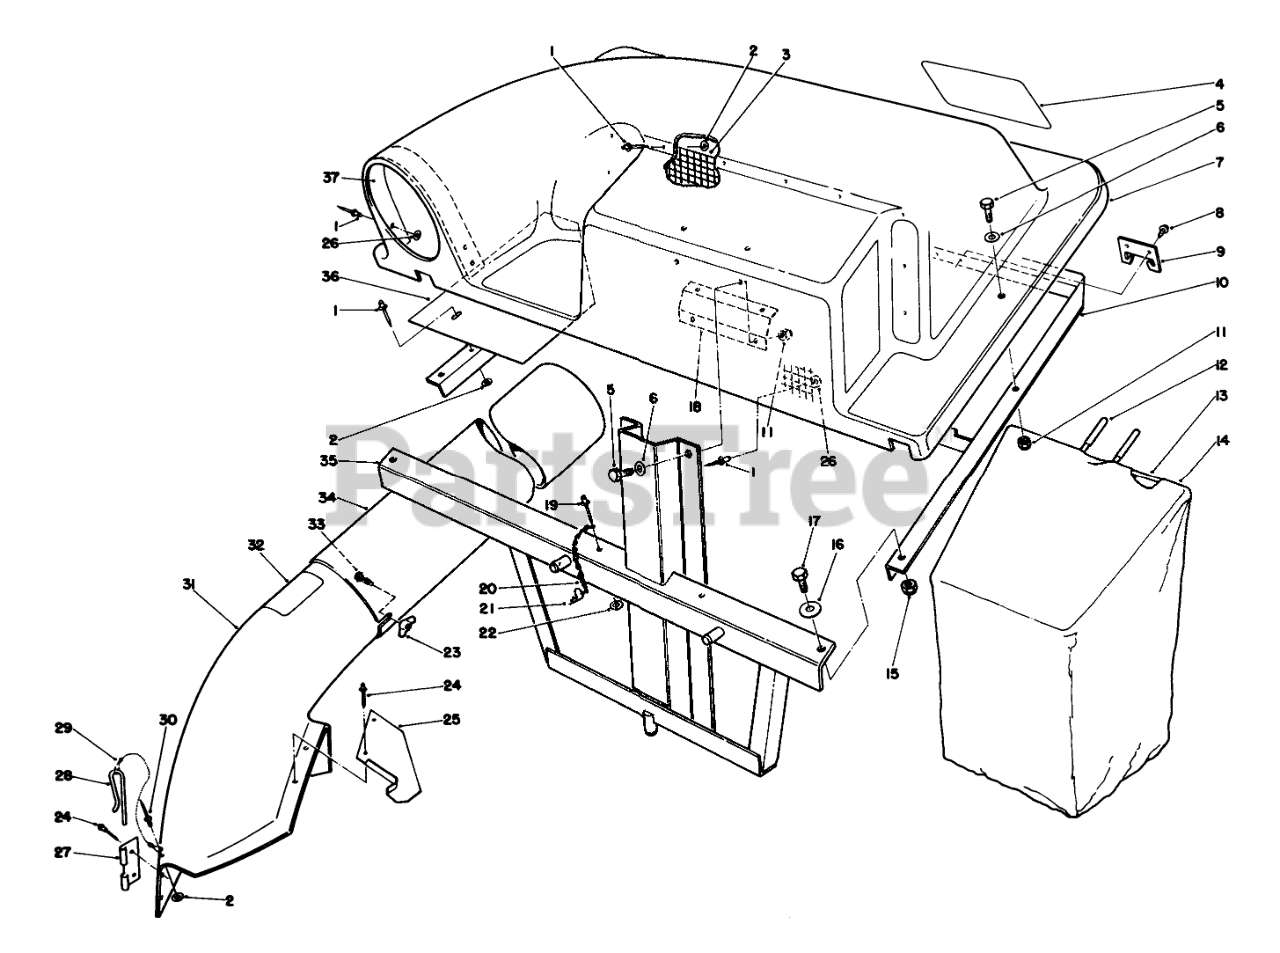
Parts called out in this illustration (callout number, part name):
1	RIVET-POP
2	Washer
3	SCREEN
4	DECAL-BAGGER, TWIN
5	SCREW-HH
6	WASHER-PLAIN
7	COVER-BAGGER, TWIN
8	Bolt 1/4-20
9	BRACKET-FRAME, BAG
10	Cover-Frame
11	NUT-LOCK, NI
12	GRIP-HANDLE, BAG
13	Frame-Bag
15	Locknut
16	WASHER-FLAT
17	SCREW-HH
18	Plate-Backup
19	Rivet-Pop
20	10 LINK CHAIN W/O HOOK
21	PIN-HAIR
22	WASHER-BACK
23	NUT-WING SPECL
24	RIVET-BLIND
25	CHUTE SUPT BRKT
26	WASHER-FLAT
27	BRACKET-MOUNTING, CHUTE
28	PIN-LOCKING, CHUTE
29	LANYARD
30	RIVET-BLIND
31	Chute Assembly (Incl. Ref. #24-30 & 32)
32	DECAL-DANGER
33	BOLT-CARR
34	TUBE(ROUND&LONG)
35	Frame-Mounting
36	Baffle
37	Support Inlet
